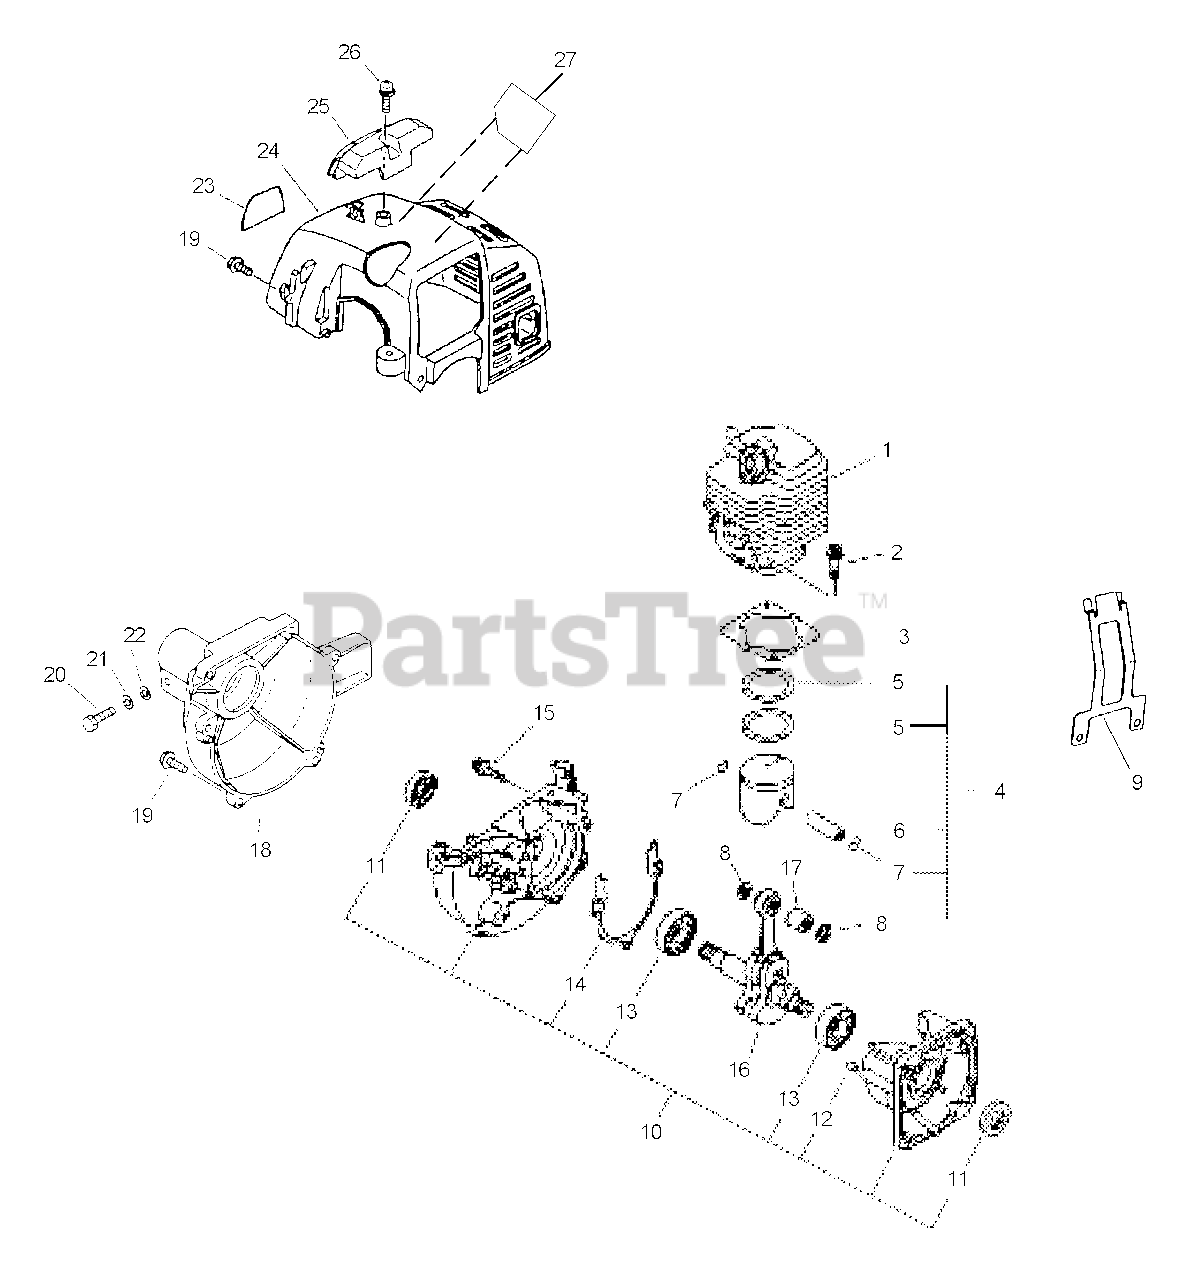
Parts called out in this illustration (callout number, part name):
1	CYLINDER
2	SCREW - 5X22
3	GASKET, CYLINDER
4	PISTON KIT
5	RING, PISTON
6	PIN, PISTON
7	RING, RETAINING
8	SPACER, PISTON
9	GUARD, ENGINE
10	CRANKCASE ASSY
11	SEAL, OIL
12	PIN - LOCATING
13	BEARING, BALL - 6201
14	GASKET, CRANKCASE
15	SCREW - 5X28
16	CRANKSHAFT ASSY
17	BEARING, NEEDLE
18	CASE, FAN - ORANGE
19	SCREW - 4X16
20	BOLT - 5X25
21	LOCKWASHER - 5
22	WASHER - 5
23	LABEL - MODEL
24	COVER, ENGINE - ORANGE
25	GUARD, TOP - BLACK
26	SCREW - 5X16 -- TAPPING
27	LABEL - CAUTION
